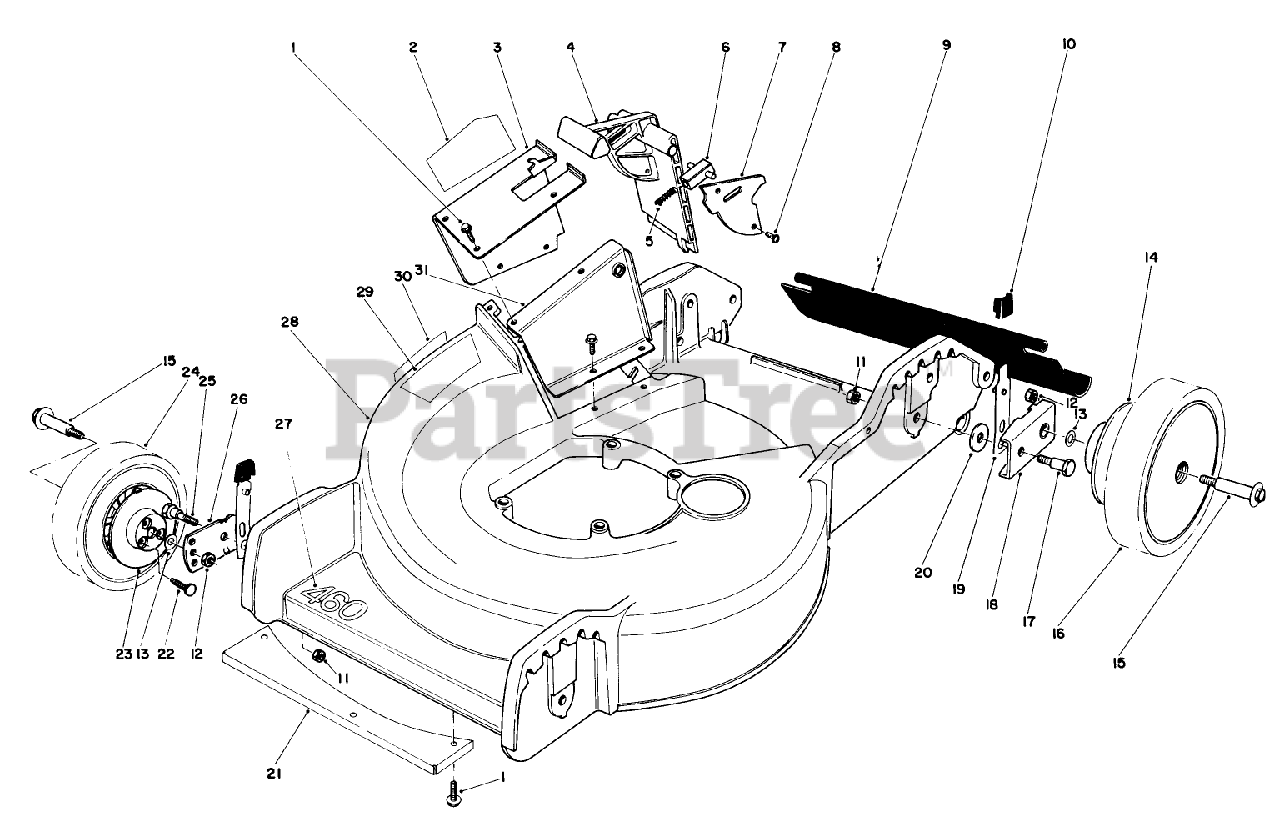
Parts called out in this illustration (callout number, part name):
1	SCREW
5	SPRING-COMPRESSION, LATCH
9	SHIELD - TRAILING
10	KNOB-ARM
11	NUT-LOCK, NI
13	WASHER
15	BOLT-WHEEL
17	PIVOT SCREW
18	HP PIVOT ARM ASM
19	SPRING ARM ASM
20	PIVOT WASHER
22	SCREW-DRIVE
23	Wheel Cover Inner
25	PIVOT SCREW
26	PIVOT ARM ASSY
30	STEP PAD DECAL
